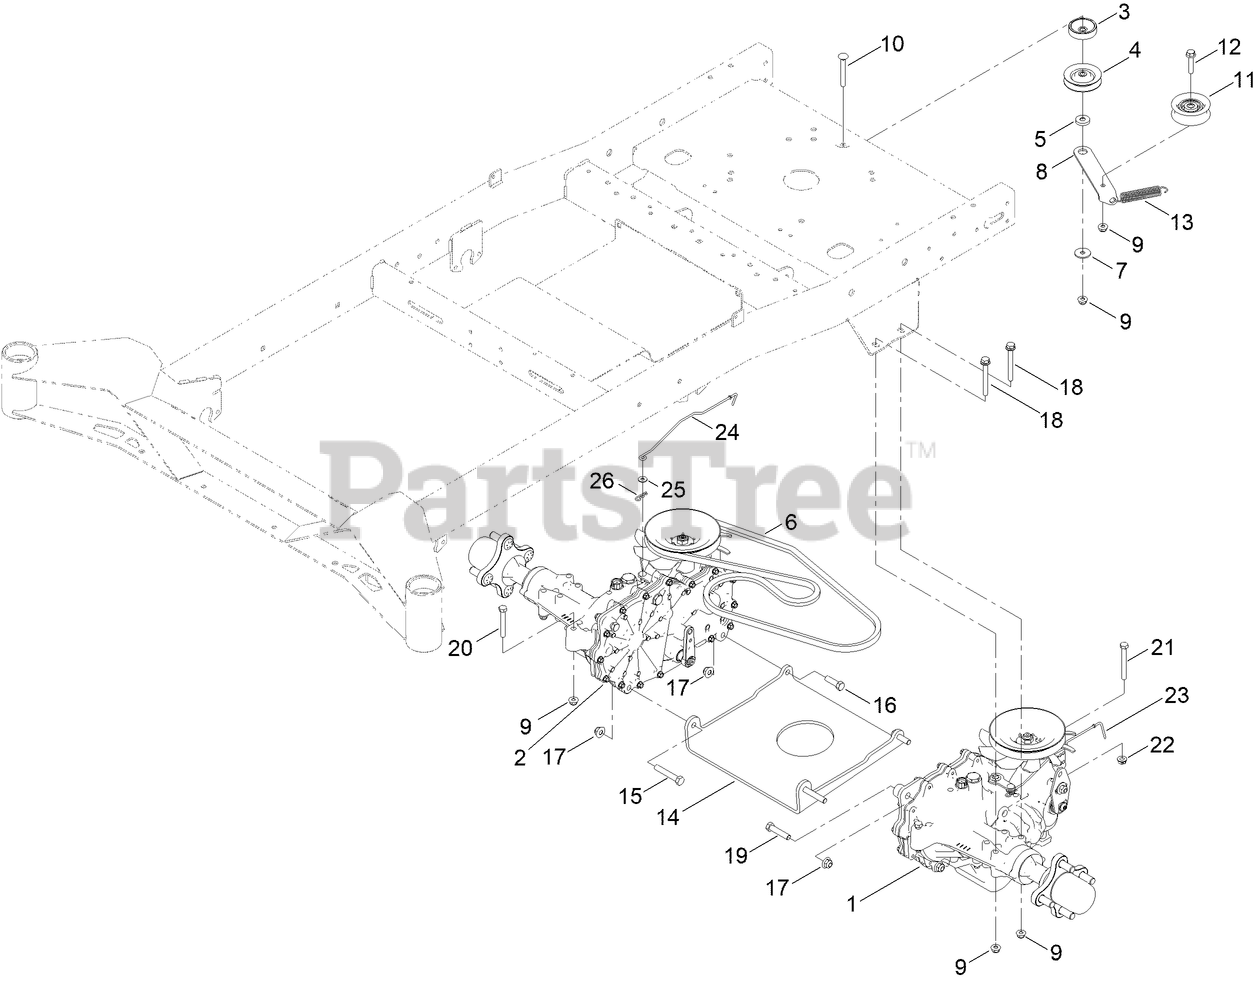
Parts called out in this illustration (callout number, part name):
1	LH HYDRO TRANSAXLE ASM
2	RH HYDRO TRANSAXLE ASM
3	SPACER
5	SPACER-IDLER ARM
6	V-BELT (A SEC 66.30 EL)
7	WASHER-PIVOT
8	ARM-IDLER
9	NUT-HF
10	SCREW-CARR
11	PULLEY-IDLER, FLAT
12	SCREW-HHF
13	SPRING-PEDAL, RETURN
14	PLATE-HYDRO [BLACK]
15	SCREW-HH
16	SCREW-HH
17	NUT-HF, NI
18	SCREW-HHF
19	SCREW-HH
20	SCREW-HH
21	SCREW-HH SPCL
22	NUT-HF
23	ROD-BYPASS, LH
24	ROD-BYPASS, RH
25	WASHER
26	PIN-HAIR
